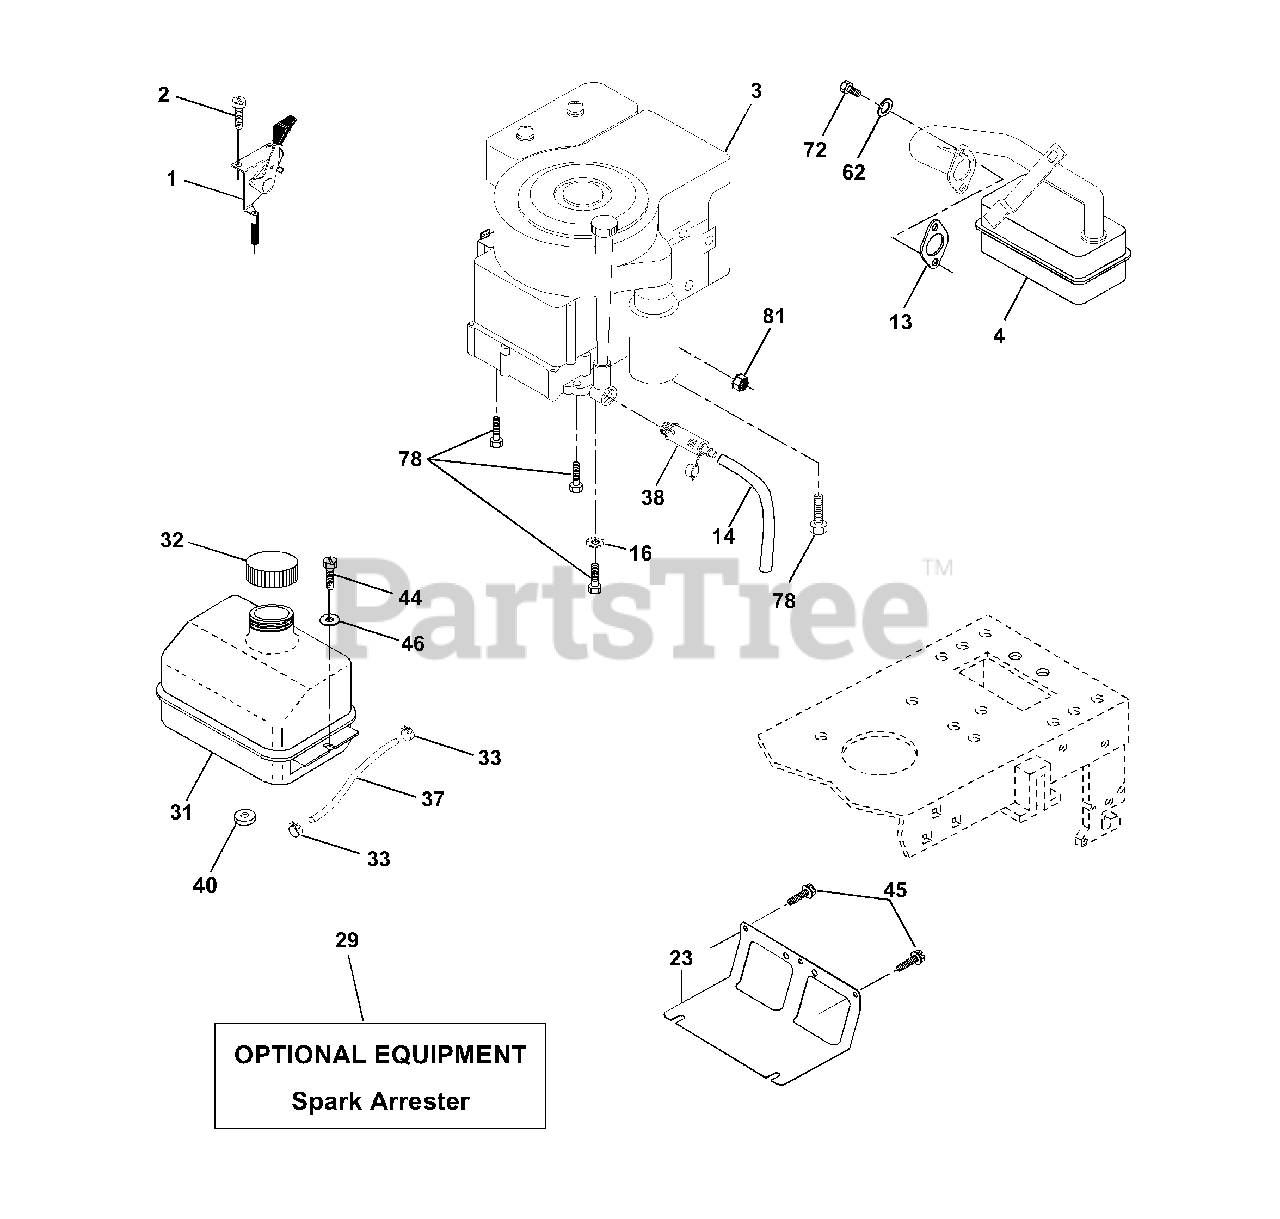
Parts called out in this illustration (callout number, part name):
1	Control Th/ch
2	Screw Hex Thd Cut 1/4-20x5/8 T
4	Muffler
13	Gasket Eng 1 313 Id Tin Plated
14	Tube Drain Oil Easy
16	Washer Lock Ext Tooth 3/8
23	Shield Browning
29	Kit Spark Arrestor (Flat Scrn)
31	Tank Fuel Front 1 25
32	Cap Asm Fuel
33	Clamp Hose Blk
37	Line Fuel 20"
38	Plug Drain Oil Easy
40	Bushing Snap Nyl Blk Fuel Line
44	Screw Hexwsh Thdrol 1/4-20 x 3/4
45	Screw Hex Wsh Thdrol 3/8-16
46	Washer 9/32 x 7/8 x 16 ga
62	Washer Lock Hvy Hlcl Spr 5/16
72	Screw Hexhd Cap 5/16-18 x 3/4
78	Screw 3/8-16 x 1-1/4
81	Nut Keps Hex 1/4-20 UNC
